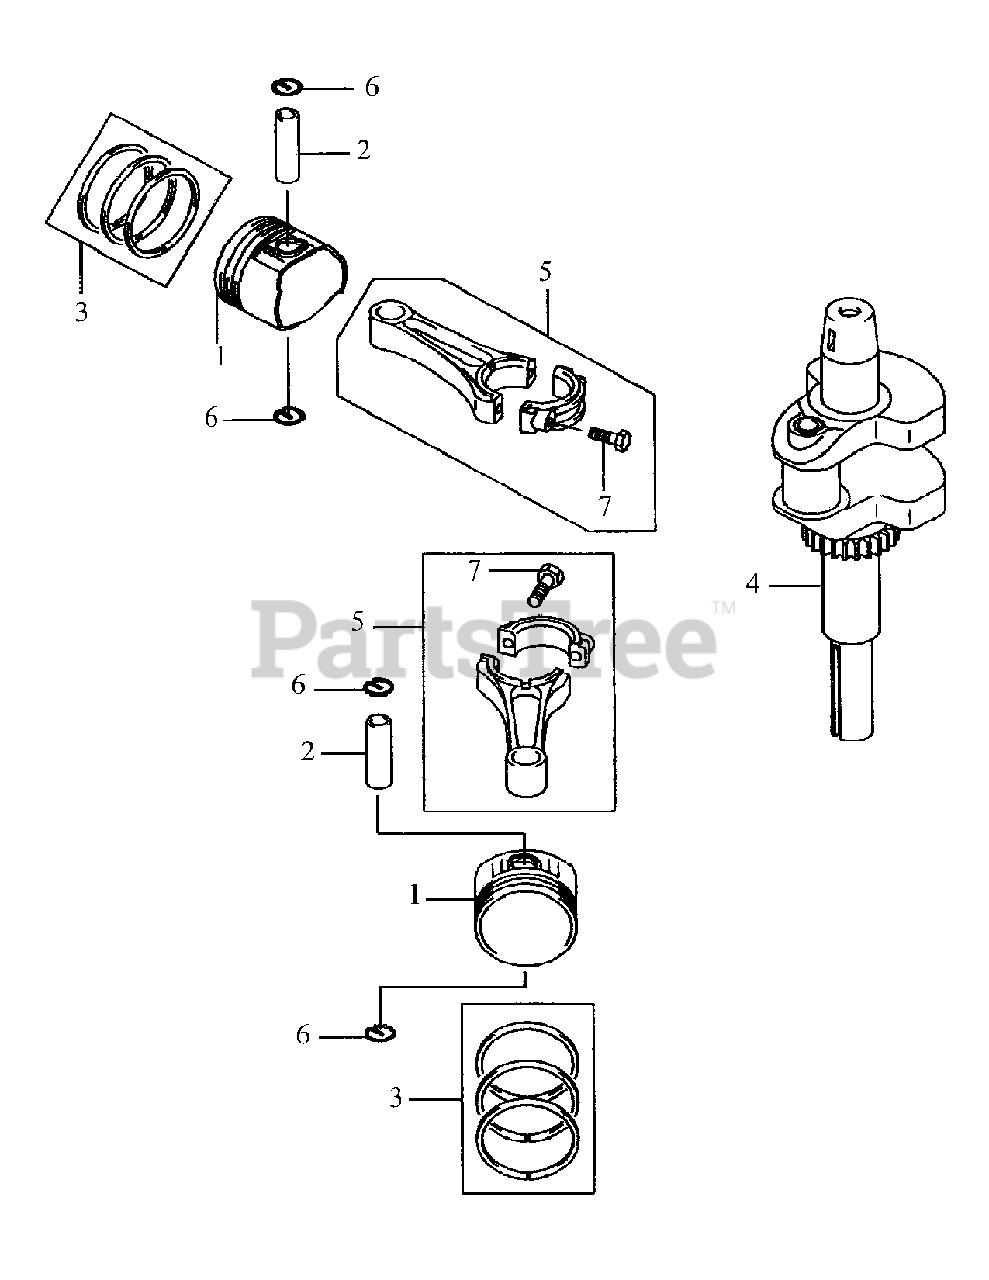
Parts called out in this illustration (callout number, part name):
1	Piston, Engine
1	Piston, Engine 0.50mm o/s
3	Ring, Set Piston
3	Ring, Set Piston 0.50mm o/s
4	Crankshaft, Complete
5	Rod, Assy Connecting
5	Rod, Assy Connecting, 0.50 u/s
7	Bolt, Flanged
